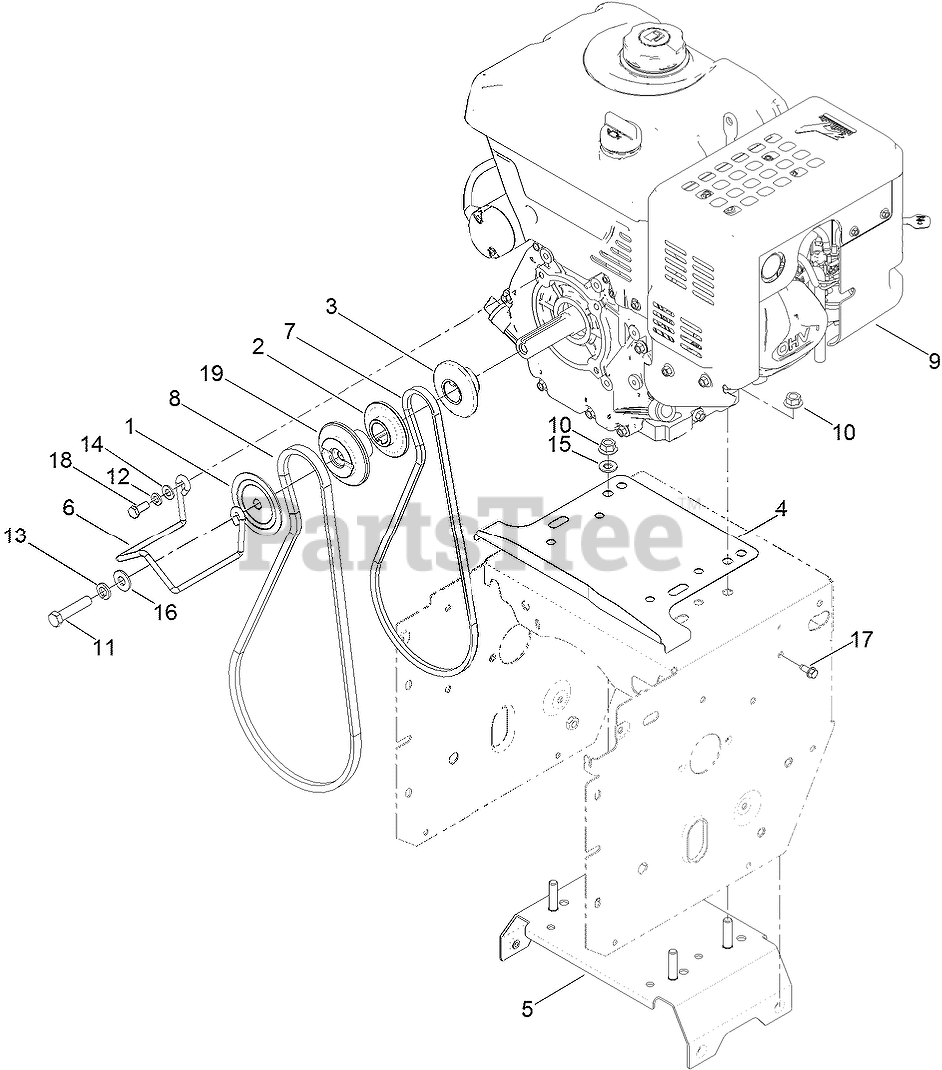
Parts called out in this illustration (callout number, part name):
1	SHEAVE-HALF, IMPELLER
2	PULLEY-ENGINE, TRACTION
3	SHEAVE-HALF, TRACTION
4	SHIELD-DRIVE
5	FRAME BRACE ASM
6	GUIDE-BELT
7	BELT-V
8	BELT-V
9	ENGINE-175FDS-1
10	NUT-FLANGE
11	SCREW-HH
12	WASHER-LOCK
13	WASHER-LOCK
14	WASHER-PLAIN
15	WASHER-FLAT
16	WASHER-FLAT
17	SCREW-HWH
18	SCREW-HH
19	PULLEY-ENGINE, IMPELLER
